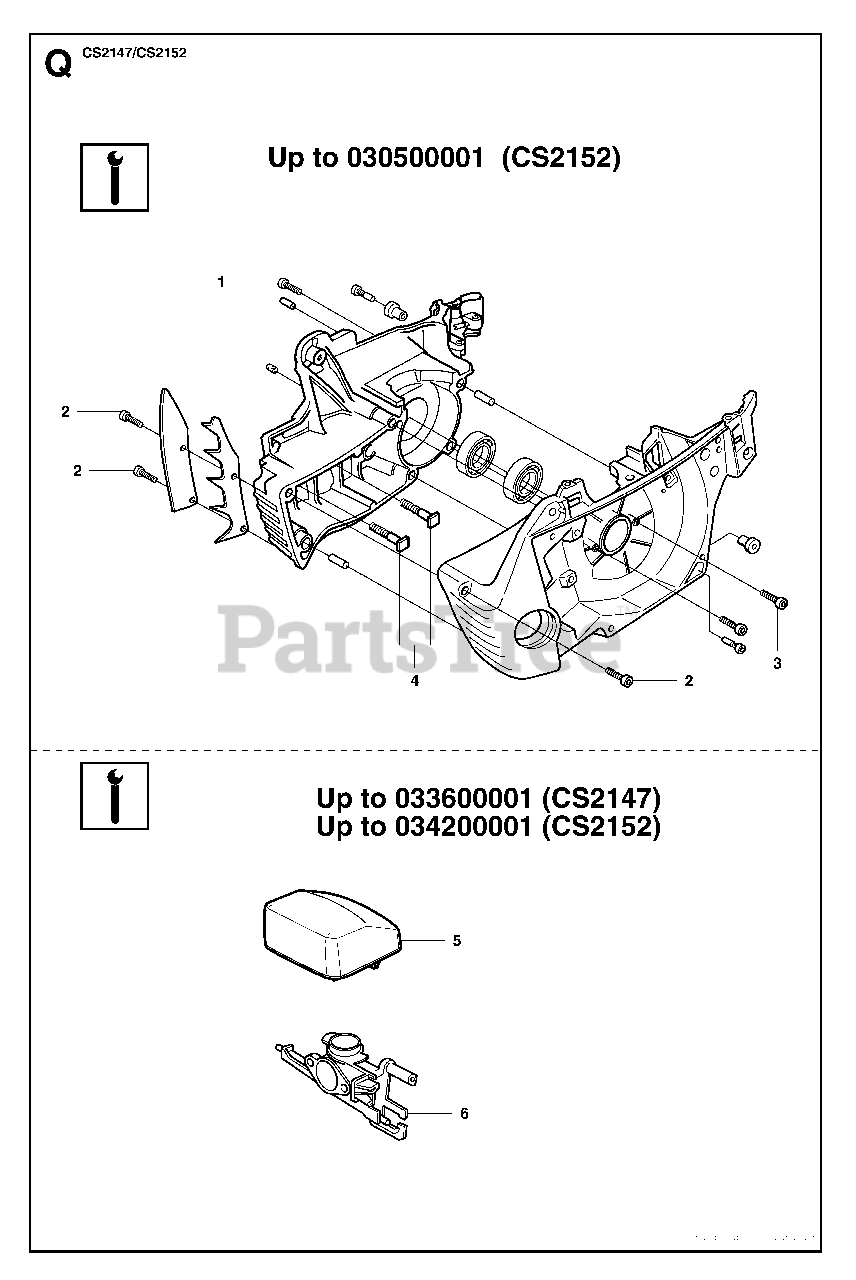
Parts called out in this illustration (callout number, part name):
5	AIR FILTER - NYLON (B)
5	AIR FILTER - NYLON (Y)
5	AIR FILTER - FELT
